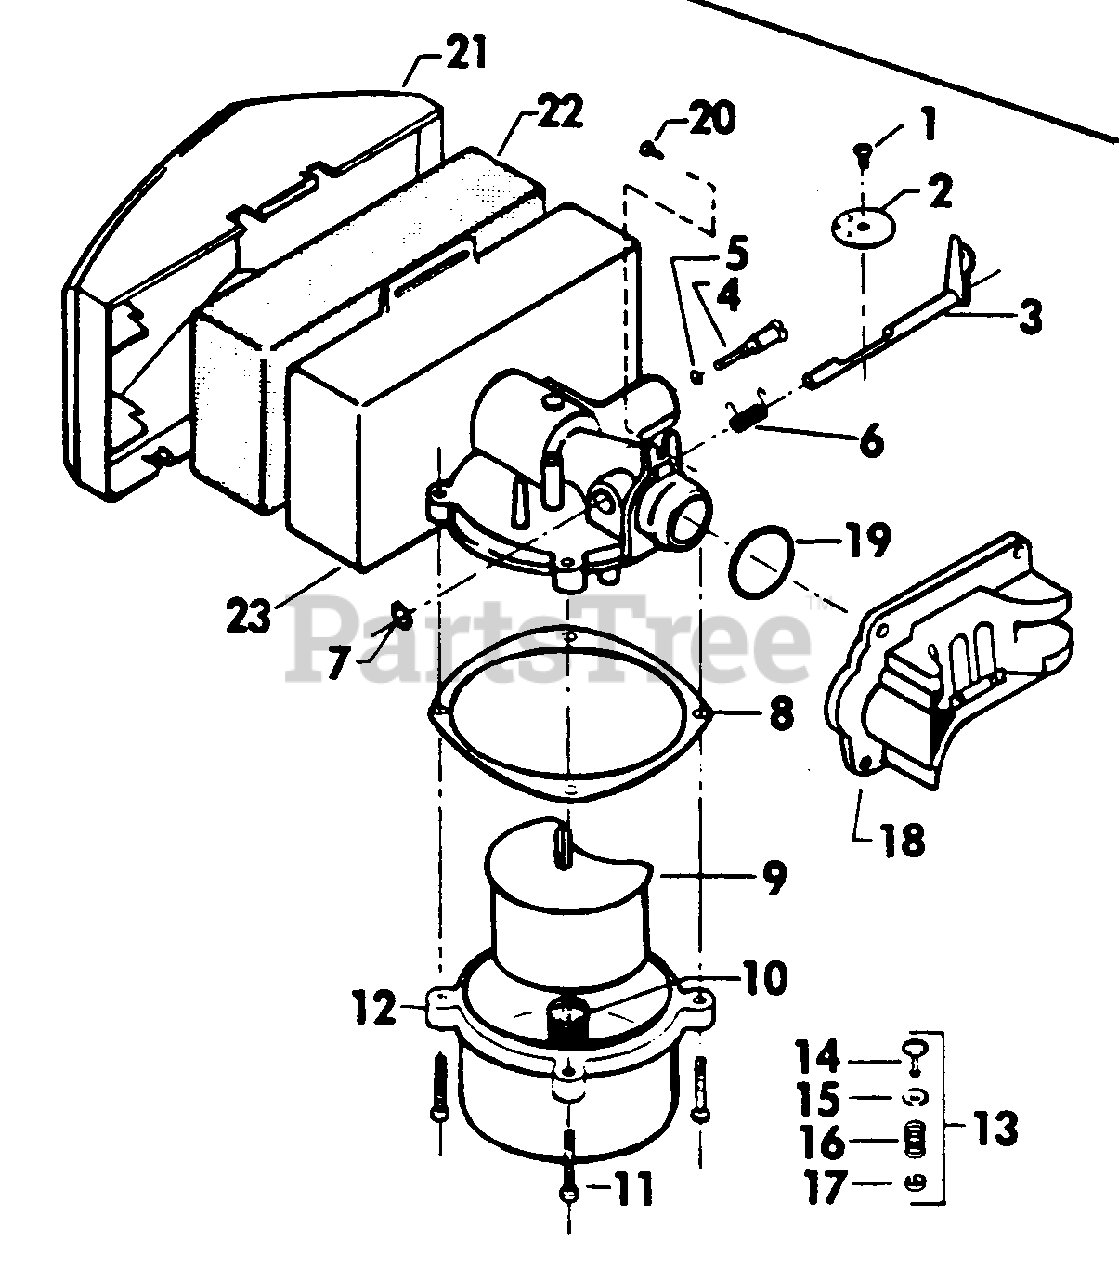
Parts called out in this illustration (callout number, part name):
1	Screw, Disk
2	Disk, Throttle
3	Throttle Shaft
4	Screw, Alt. Adj.
6	Spring, Throttle
7	Grip, Ring
8	Gasket, Bowl
9	Float & Valve
10	Spring, Float
11	Screw, Bowl
14	Valve Stem
15	Valve Seat
16	Valve Spring
17	Valve Keeper
18	Reed Plate
20	Screw, Mtg.
21	Cover, Filter (Deluxe)
22	Element
23	Carb. Body Assy.
